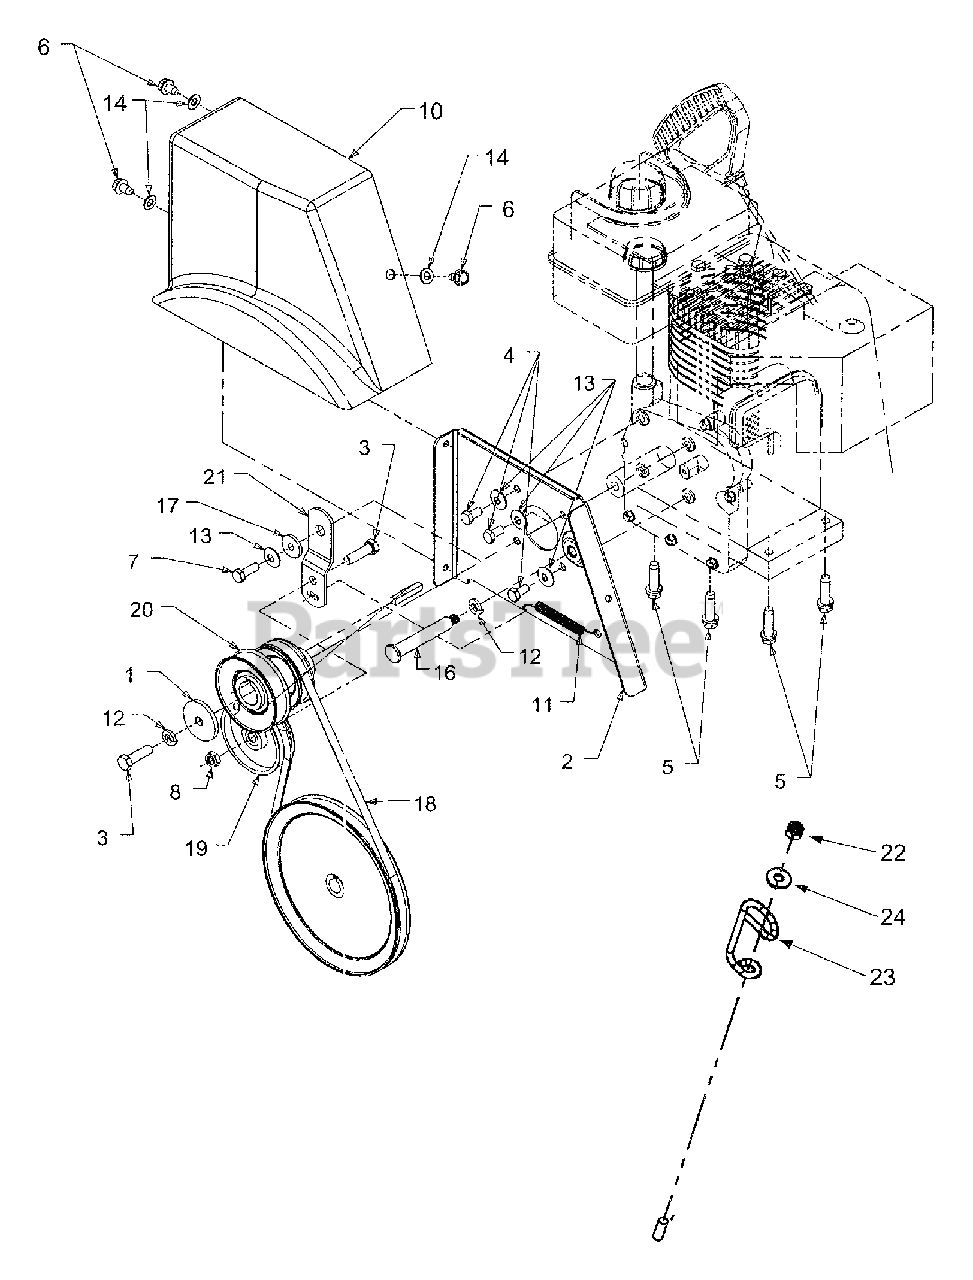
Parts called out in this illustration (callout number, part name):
1	Washer .390 I.D. x 1.75
2	Brkt Asm:Cvr:Belt
3	Hex Head Screw
4	Hex Hd. Screw 5/16-24 x .625
5	Hex TT Tap Scr. 3/8-16 x 1.25" Lg.
6	Hex Wash. Screw 5/16-18
7	Hex Lock Screw 5/16-24 x .875
8	Jam Nut 3/8-24 Thd.
10	Belt Cover
11	Spring:Extension
12	L-Wash. 3/8
13	Bell-Wash. .340 I.D. x .872 O.D.
14	Fl-Wash. .330 I.D. x .630 x .06
16	Shld. Screw .498 x 2.99 Lg.
17	Shld. Spacer
18	Variable Speed Belt
19	Fl-Idler Pulley 3.0" Dia.
20	Double Pulley
21	Idler:Brkt
22	Hex Lock Nut 1/4-20
23	Cable Control Wire
24	Fl-Wash. .28 x .74 x .063
